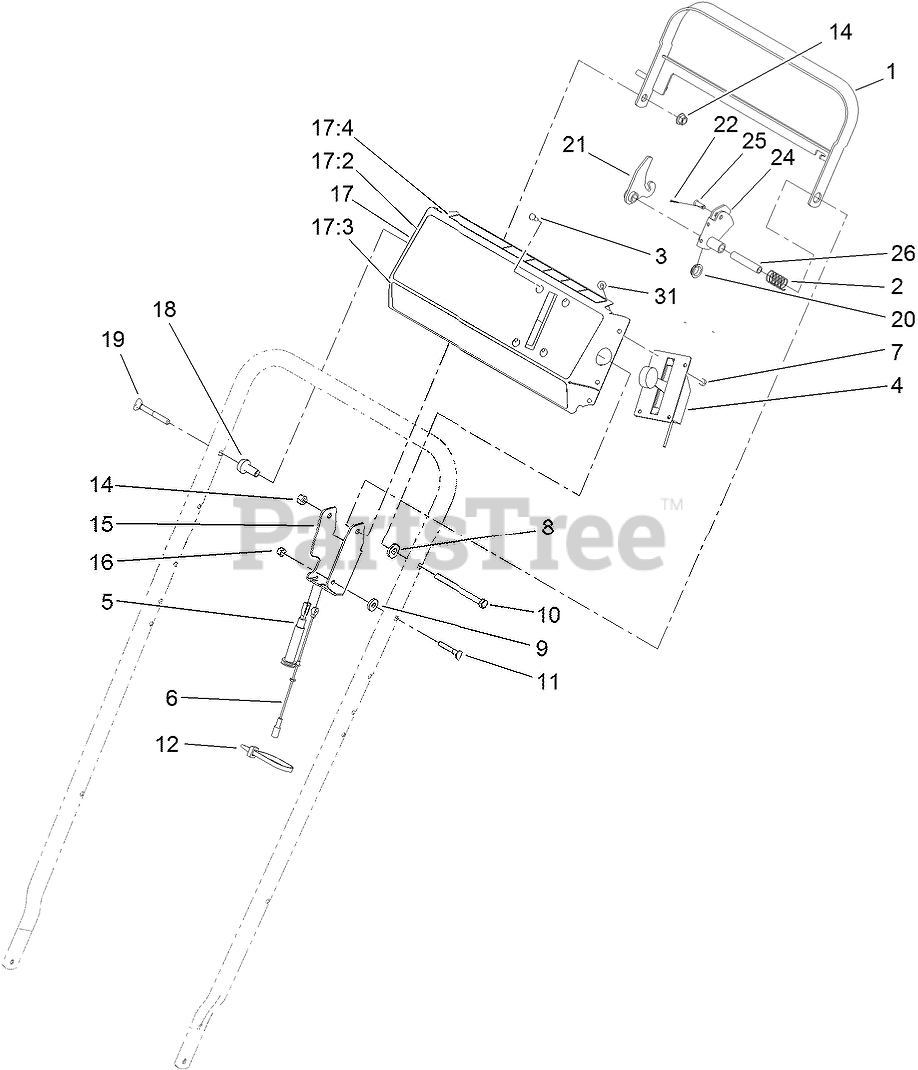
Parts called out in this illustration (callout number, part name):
1	BAR-CONTROL
2	SPRING-CONTROL
3	SCREW-PPH
4	CONTROL-THROTTLE
5	CABLE-TRACTION
6	CABLE-CLUTCH
7	NUT-LOCK, NI
8	SPACER
9	SPACER
10	SCREW-HH
11	SCREW-HANDLE
12	TIE-CABLE
14	NUT-HF, NI
15	BRACKET-CONTROL
16	NUT-LOCK, NI
17	PANEL ASM
17:2	DECAL-PANEL
17:3	Decal-Panel
17:4	DECAL-DANGER PANEL
18	SPACER-SUPPORT
19	SCREW
20	BUSHING-FLANGE
21	LEVER-TRACTION
22	PIN-COTTER
24	LEVER-BBC
25	PIN-CABLE
26	SPACER-BRACKET, CONTROL
31	SCREW-HWHTF
